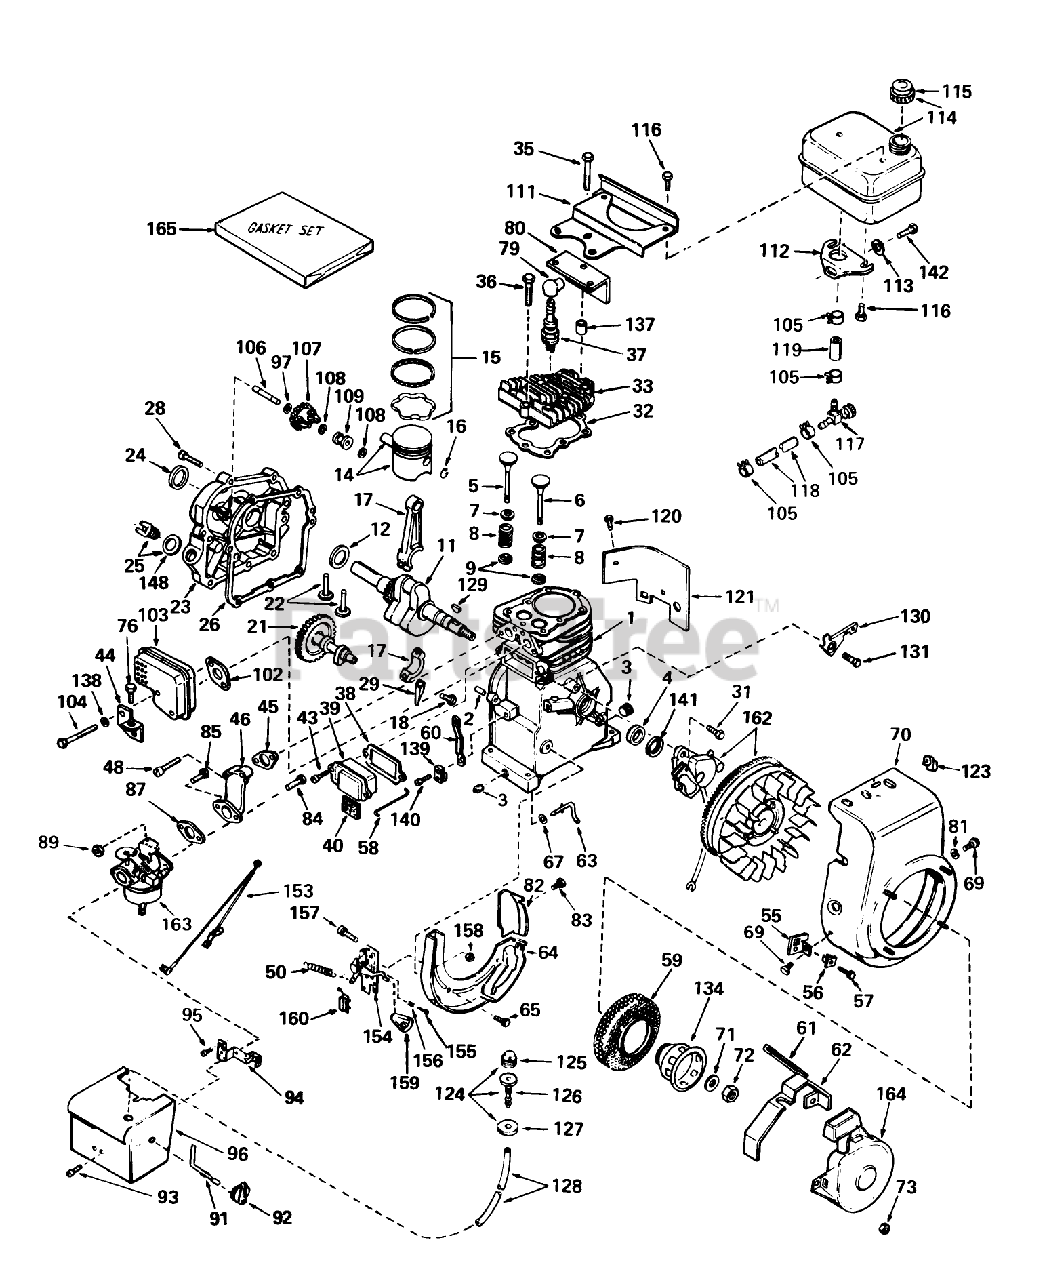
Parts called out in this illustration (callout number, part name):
1	Cylinder Assy. (Incl. #2, 3 4)
2	Pin-Dowel
3	Plug-Drain, Oil (SQH 1/4-18)
4	Seal-Oil
5	Valve, Intake (Standard) (Incl. Nos. 7, 9 10)
5	Valve, Intake (1/32" Oversize) (Incl. Nos. 7, 9 10)
6	Valve, Exhaust (Standard) (Incl. Nos. 8, 9 10)
6	Valve, Exhaust (1/32" Oversize) (Incl. Nos. 8, 9 10)
7	Cap-Upper Valve Spring
8	Spring-Valve
9	Cap-Valve, Spring
11	Crankshaft Assembly
12	Washer-Thrust
14	Piston Pin Assy. (Incl . Ref. . #14) (Std.)
14	Piston, Pin Ring Assy. (Std.)(Incl. Ref. #13A, 14 15)
14	Piston Pin Assy. (Incl. Ref. #14) (.010 Oversize)
14	Piston,Pin Ring Assy. (.010 over-size)(Incl. Ref. #13A, 14 15)
14	Piston Pin Assy. (.020 oversize) (Incl. Ref. #14)
14	Piston, Pin Ring Assy. (Incl. Nos. 13A, 14 15)(.020 oversize)
15	Ring Set Piston (Std.)
15	Ring Set Piston (.010 Oversize)
15	Ring Set Piston (.020 Oversize)
16	Ring-Retaining, Piston Pin
17	Rod Assembly, Connecting (Incl. Nos. 17 18)
18	Bolt-Rod, Connecting
21	Camshaft
22	Lifter-Valve
23	Cover, Cylinder (Incl. Nos. 24, 25, 106 148)
24	Seal-Oil
25	Plug-Fill, Oil
26	Gasket-Cylinder Cover
28	Screw
29	Dipper-Oil
31	Screw
32	63573 GIL 42 SNWTHW
33	Head Cylinder
35	Screw (5/16-18 X 2)
36	Screw (5/16-18x1-1/2)
37	Plug, Spark (J17LM or equiv.)
37	Plug, Spark (Champion RCJ-8)
38	Gasket Breather
39	Breather Assembly (Incl. Nos. 52 84)
40	Element-Breather
43	Screw
44	Bracket-Cover, Carburetor
45	Gasket, Intake
46	Pipe, Intake
48	Screw (1/4-20 x 1-19/32)
50	Spring-Extension
55	Bracket
56	Grommet
57	Screw
58	Link-Governor to Throttle
59	Screen-Starter
60	Lever, Governor
61	Seal, Snowguard
62	Guard-Starter
63	Rod-Governor
64	Baffle-Blower Housing
65	Screw (1/4-20x19/32)
67	Washer-Flat
69	Screw
70	Housing, Blower
71	Washer-Spring
72	Hex Nut
73	Nut and Lock Washer (1/4-28)
76	Screw (10-24 x 3/8)
79	Cover-Spark Plug
80	Baffle-Heat
81	Washer
82	Baffle-Extension
83	Screw-Hex Washer Hd.
85	Screw-Fil. Hd.
87	Gasket
89	Nut and Lock Washer (1/4-28)
91	Rod-Choke
92	Knob-Control
93	Screw (8-32 X 5/16)
94	Bracket-Choke
95	Screw (10-32 x 1/2)
96	Cover, Carburetor
97	Washer-Flat
102	Gasket-Intake
103	Muffler
104	Screw-Fil. Hd.
105	Clamp-Line, Fuel
106	Shaft-Governor
107	Governor Gear ASM
108	Ring-Retaining
109	Spool, Governor
111	Plate-Fuel Tank
112	Bracket, Fuel Tank Lower
113	Washer
114	53023/VAR.10/16HP O
115	Cap, Fuel
116	Screw (1/4-15x7/8)
117	Valve-Shut Off
118	Line-Fuel
119	Line-Fuel (8.62)
120	Screw
121	Extension-Blower
123	51004 GIL ROTARY TI
124	Primer Assy. (Incl. Nos. 89, 90 91)
125	Bulb, Primer
126	Body, Primer
127	Retainer, Primer Bulb
128	Line, Primer
129	Key, FIywheel
130	Bracket-Hold Down
131	Screw (10-24 x 9/16)
134	Cup, Starter
137	pacer
138	Washer
139	Clamp-Lever, Governor
140	Screw
141	Gasket Stator
142	Screw Assembly
148	Gasket
153	Wire-Ground
154	Control Assembly, Speed (Incl. Ref. #155 thru 158 160)
155	Screw
156	Spring-Compression
157	Screw
158	Nut-Lock
159	Knob-Control
160	Terminal
162	Magneto
163	Carburetor (Incl. Ref. #87)
164	Starter Assy., Rewind
165	Gasket
